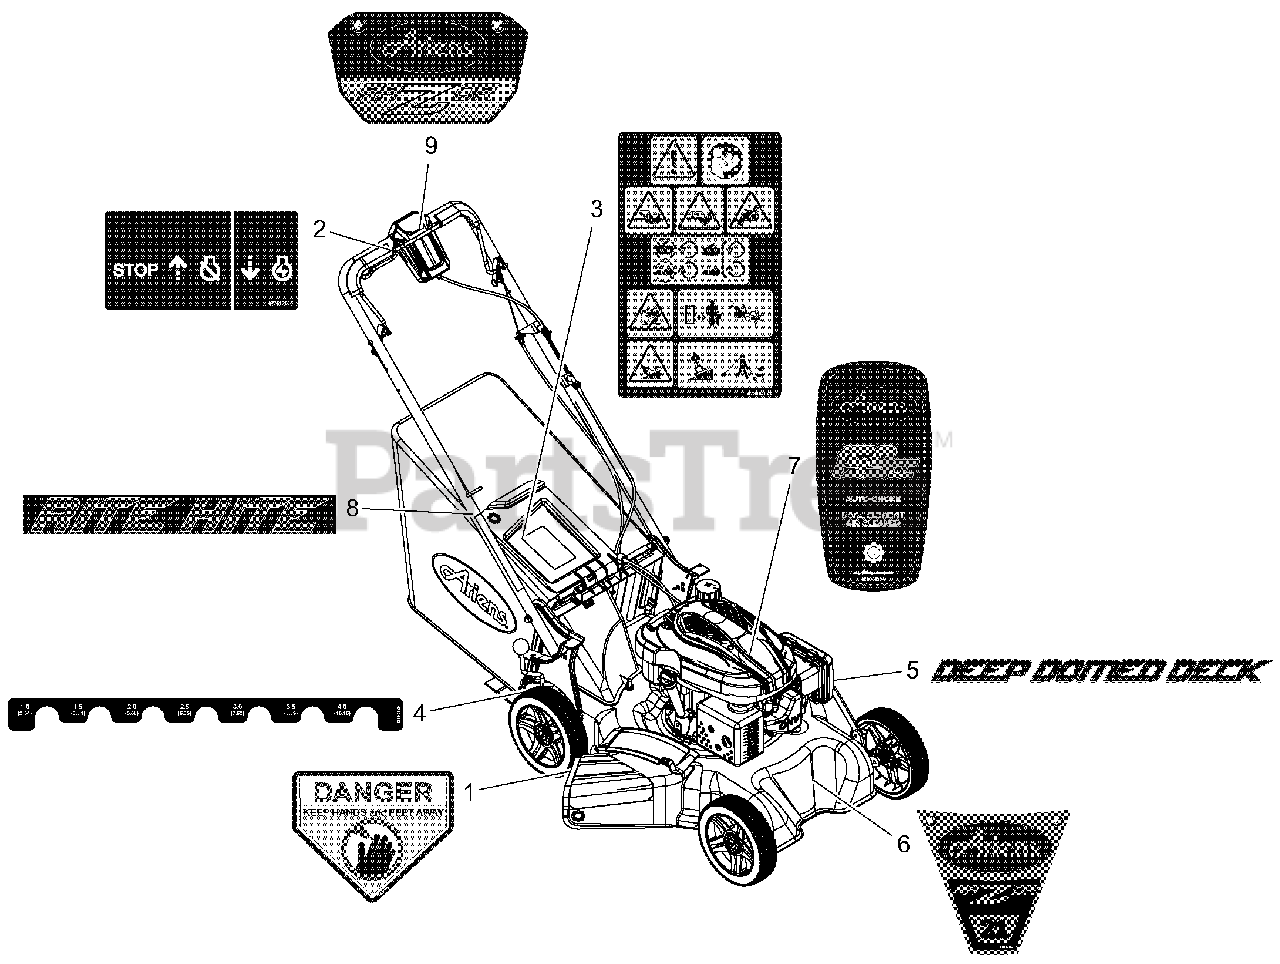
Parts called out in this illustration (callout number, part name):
1	DECAL, DANGER
2	DECAL - ENGINE CONTROL
3	DECAL,MAIN SAFETY_WAW LM
4	DECAL, HOC
5	DECAL, DEEP DOME DECK
6	DECAL, ARIENS RAZOR STYLE
7	DECAL, ENGINE STYLE - ARIENS
8	DECAL, RITE HITE
9	DECAL, ARIENS RAZOR - SMALL
